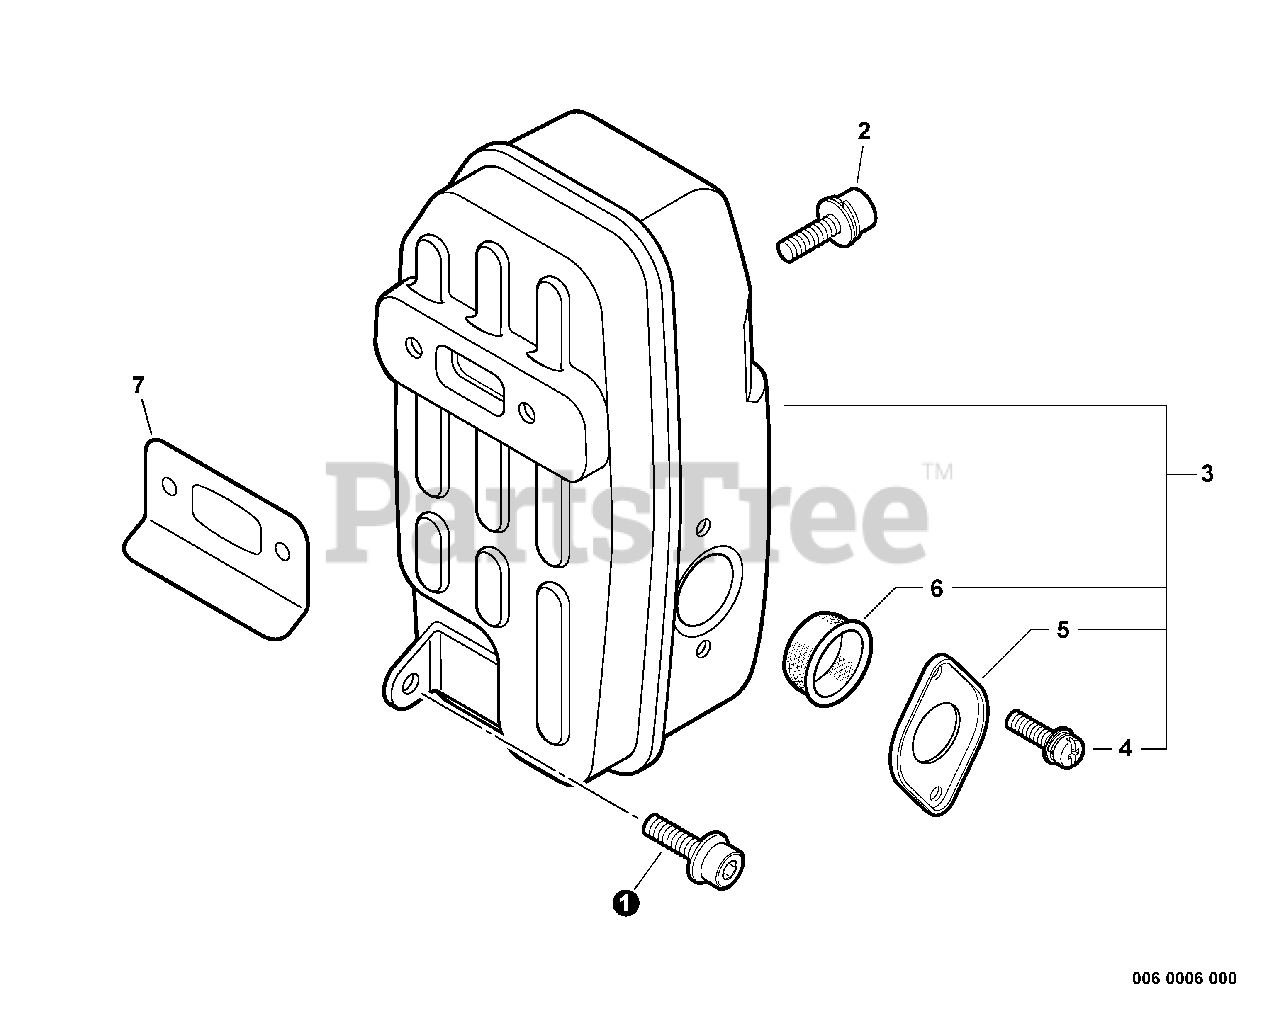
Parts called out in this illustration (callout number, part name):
1	BOLT 5×14
2	BOLT, FLANGE 6×20
3	MUFFLER ASSY
4	SCREW 4×12
5	GUIDE, EXHAUST
6	SCREEN, SPARK ARRESTER
7	GASKET, EXHAUST
